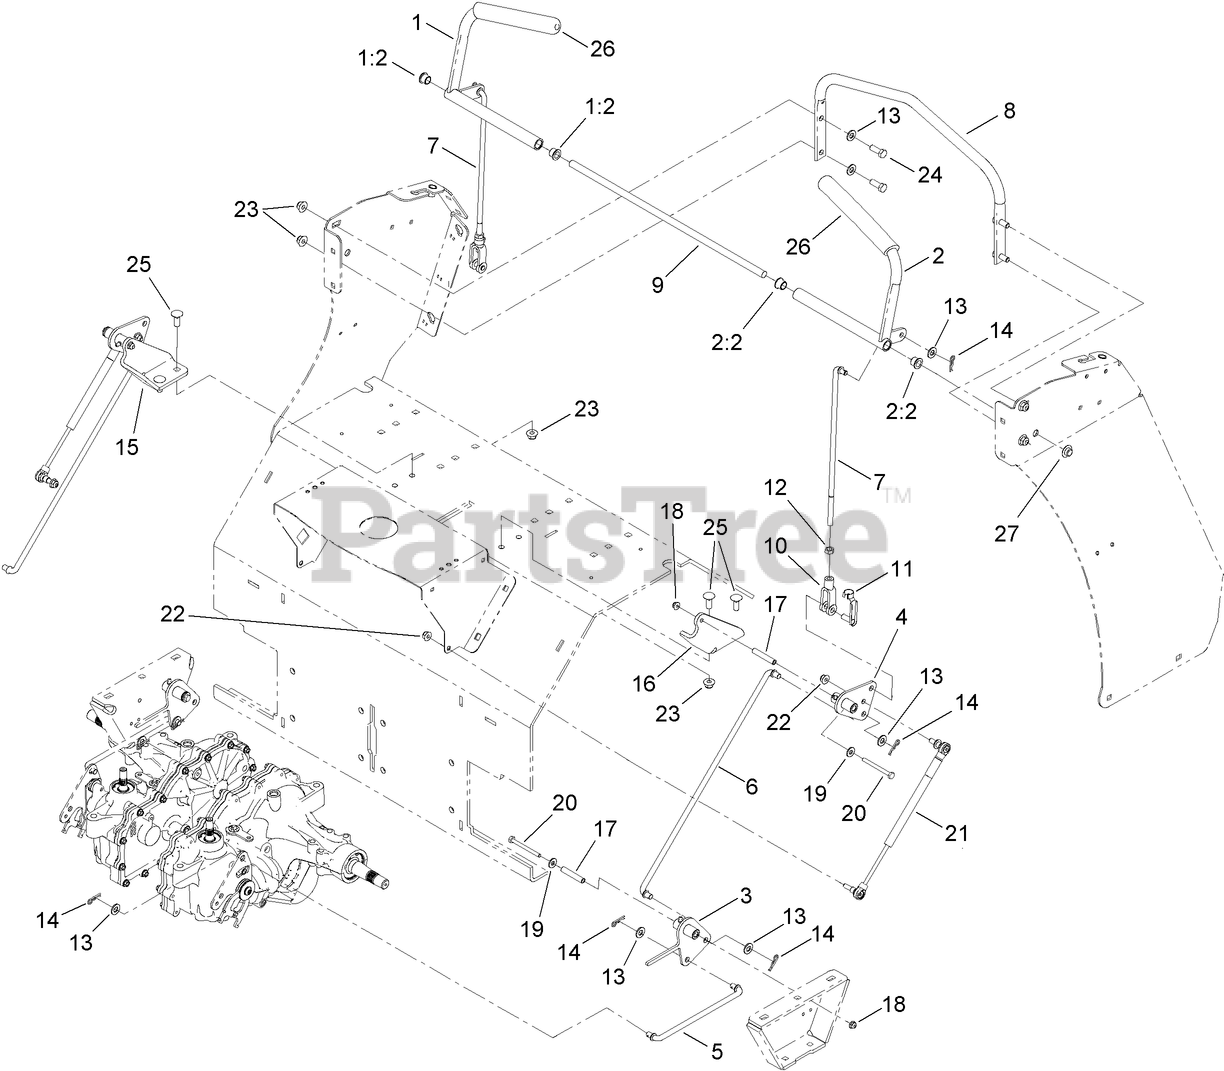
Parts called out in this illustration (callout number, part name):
1	RH CONTROL HANDLE ASM
1:2	BEARING-FLANGE
2	LH CONTROL HANDLE ASM
2:2	BEARING-FLANGE
3	BELLCRANK (W/ARM)
4	BELLCRANK (W/ARM)
5	LINK-CONTROL, HYDRO
6	LINK-BELLCRANK CONTROL
7	LINK-CONTROL, BELL CRANK
8	BAR-REFERENCE
9	SHAFT-PIVOT, CONTROL
10	YOKE-LINKAGE, BRAKE
11	Pin-Spring, Clevis
12	NUT-HEX
13	WASHER-FLAT
14	PIN-COTTER
15	BRACKET-PIVOT, RH
16	BRACKET-PIVOT, LH
17	SPACER
18	NUT-HF
19	WASHER-FLAT
20	SCREW-HH
21	DAMPER-CONTROL, MOTION
22	NUT-HF, NI
23	NUT-HF, NI
24	SCREW-HH
25	BOLT-CARR
26	GRIP-LEVER, CONTROL
27	NUT-PUSH
